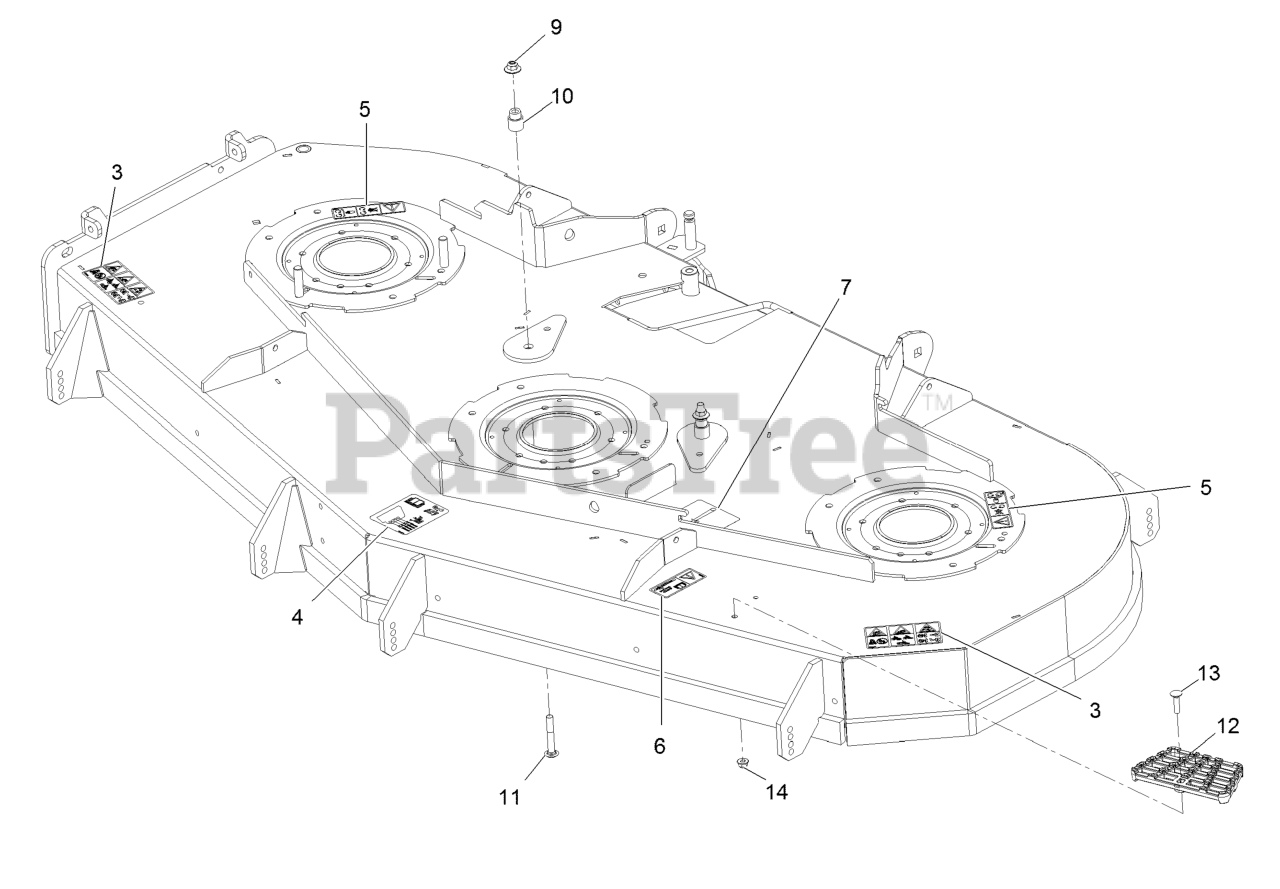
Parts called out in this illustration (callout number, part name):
3	Decal-Danger Thrown Objects
4	Decal-Roller, Anti-Scalp
5	Decal-Cover, Missing
6	Decal-Bolt Torque
7	Decal-Belt Routing
9	Nut-Flange, NI
10	Bushing, Idler
11	Screw-CARR
12	Step-Deck
13	Screw-CARR
14	Nut-HF, NI
